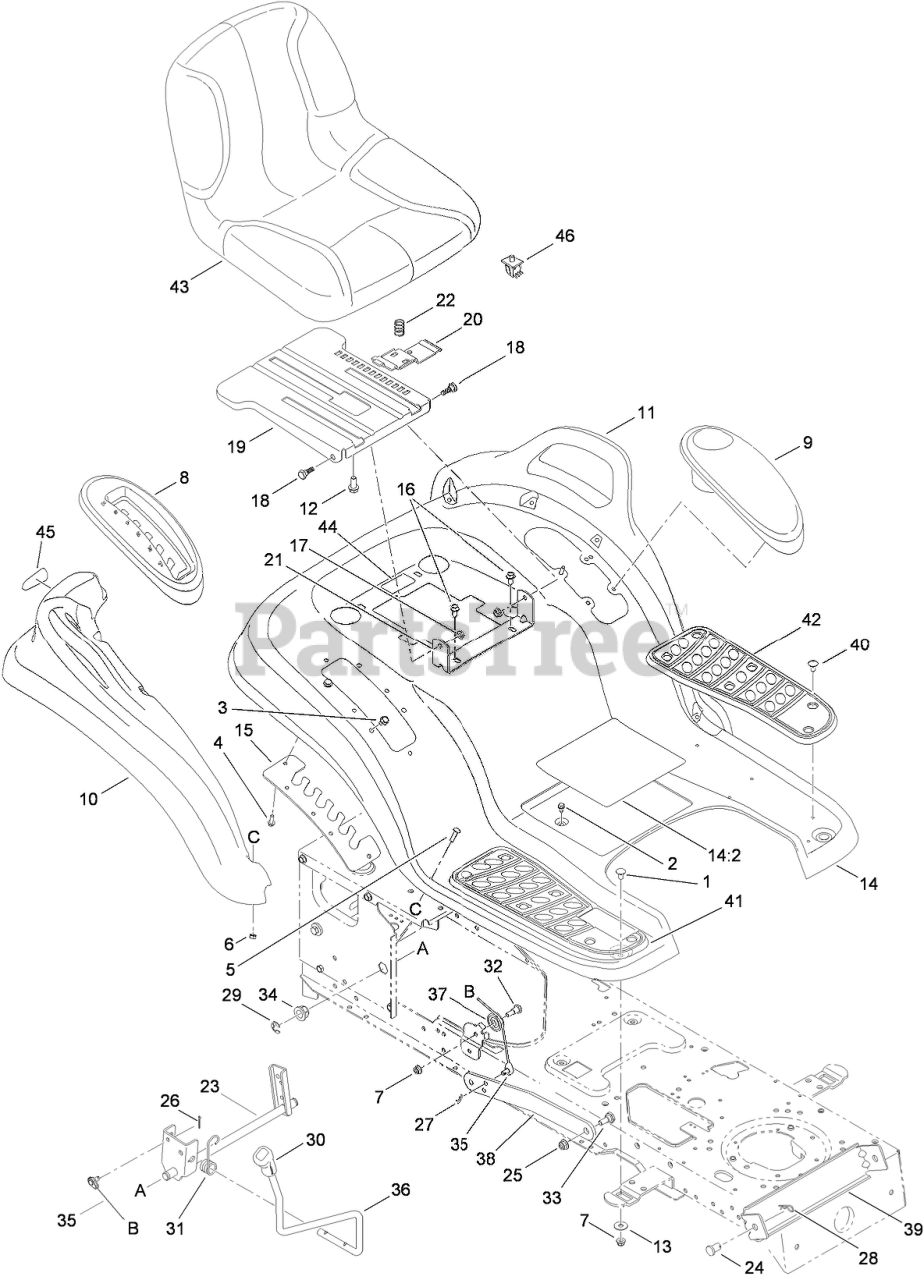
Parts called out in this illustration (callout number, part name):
1	BOLT-CARR
2	SCREW-HWHTF
3	SCREW-TAP
4	SCREW-TAP
5	SCREW-CARR
6	NUT-SEMS
7	NUT-LOCK, FLANGE
8	COVER-LEVER, LIFT
9	COVER (W/CUP HOLDER)
10	FLARE-FENDER, RH
11	FLARE-FENDER, LH
12	SCREW-HH
13	WASHER-FLAT
14	FENDER WITH DECAL
14:2	DECAL-SAFETY
15	BRACKET-ADJUSTING, LIFT
16	SCREW-TAP
17	NUT-LOCK, FLANGE
18	BOLT-SHOULDER
19	BRACKET-MOUNT, SEAT
20	LEVER-ADJUSTMENT, SEAT
21	BRACKET-PIVOT, SEAT
22	SPRING-COMPRESSION
23	LIFT SHAFT ASM
24	PIN-BRACKET, LIFT
25	NUT-LOCK, FLANGE
26	PIN-COTTER
27	PIN-COTTER
28	PIN-HAIR
29	RING-E
30	GRIP-HANDLE
31	SPRING-TORSION
32	BOLT-SHOULDER
33	BOLT-SHOULDER
34	BEARING-FLANGE
35	CABLE-LIFT
36	HANDLE-LIFT
37	PULLEY-ROLLER
38	ARM-LIFT
39	BRACKET-STABILIZER
40	CLIP-RATCHET, FASTENER
41	PAD-FOOT, RH
42	PAD-FOOT, LH
43	SEAT-HIGH
44	DECAL-TORO HOTLINE
45	REFLECTOR
46	Switch-Seat
